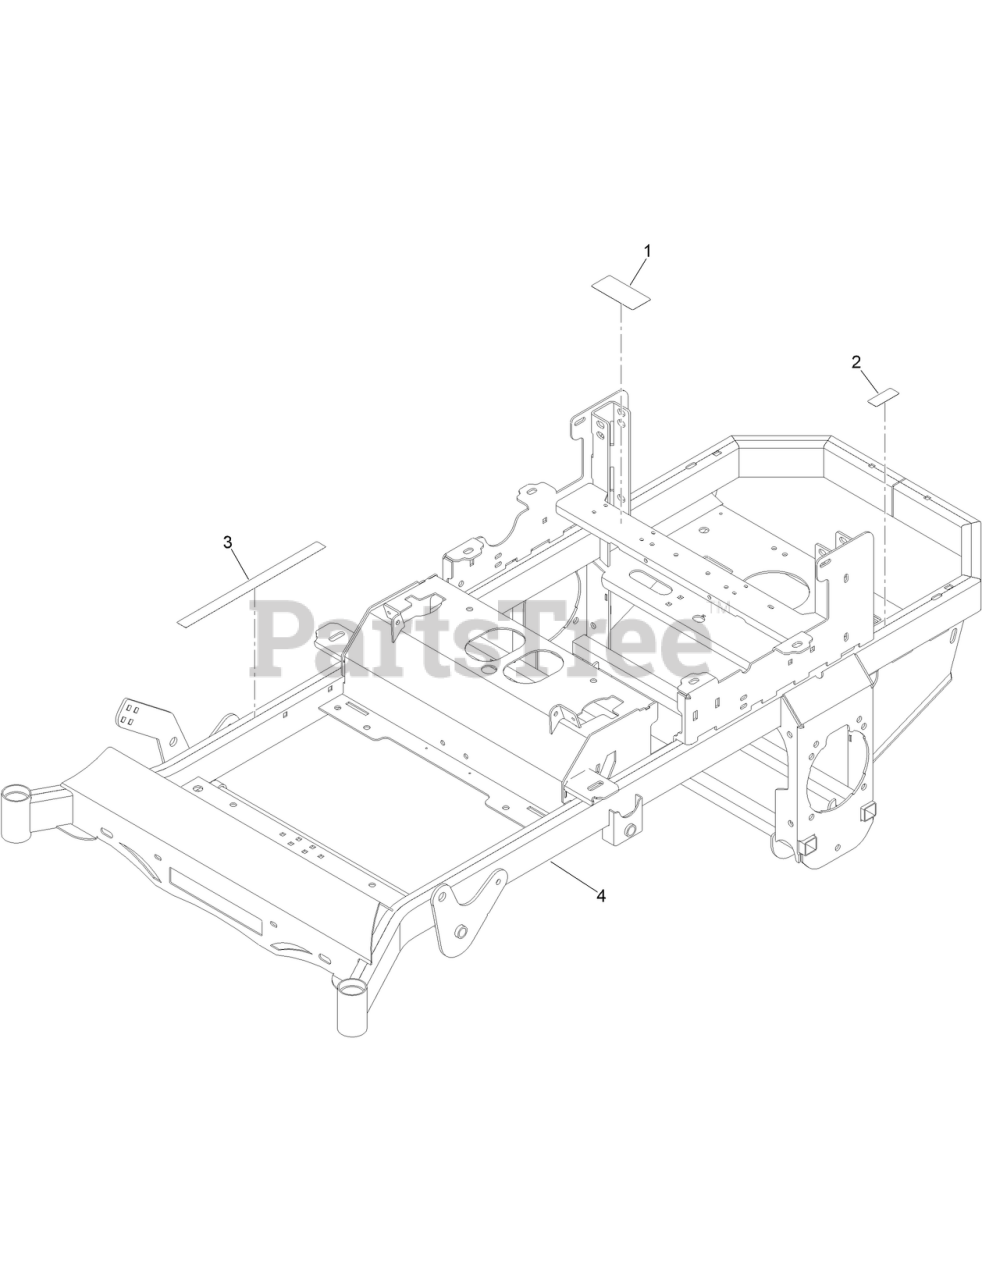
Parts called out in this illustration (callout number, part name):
1	DECAL-ROTATING FAN HAZARD
2	DECAL-HOT SURFACE
3	DECAL-WARNING(AURORA)
4	FRAME ASM - RZHD PAINTED BLACK
